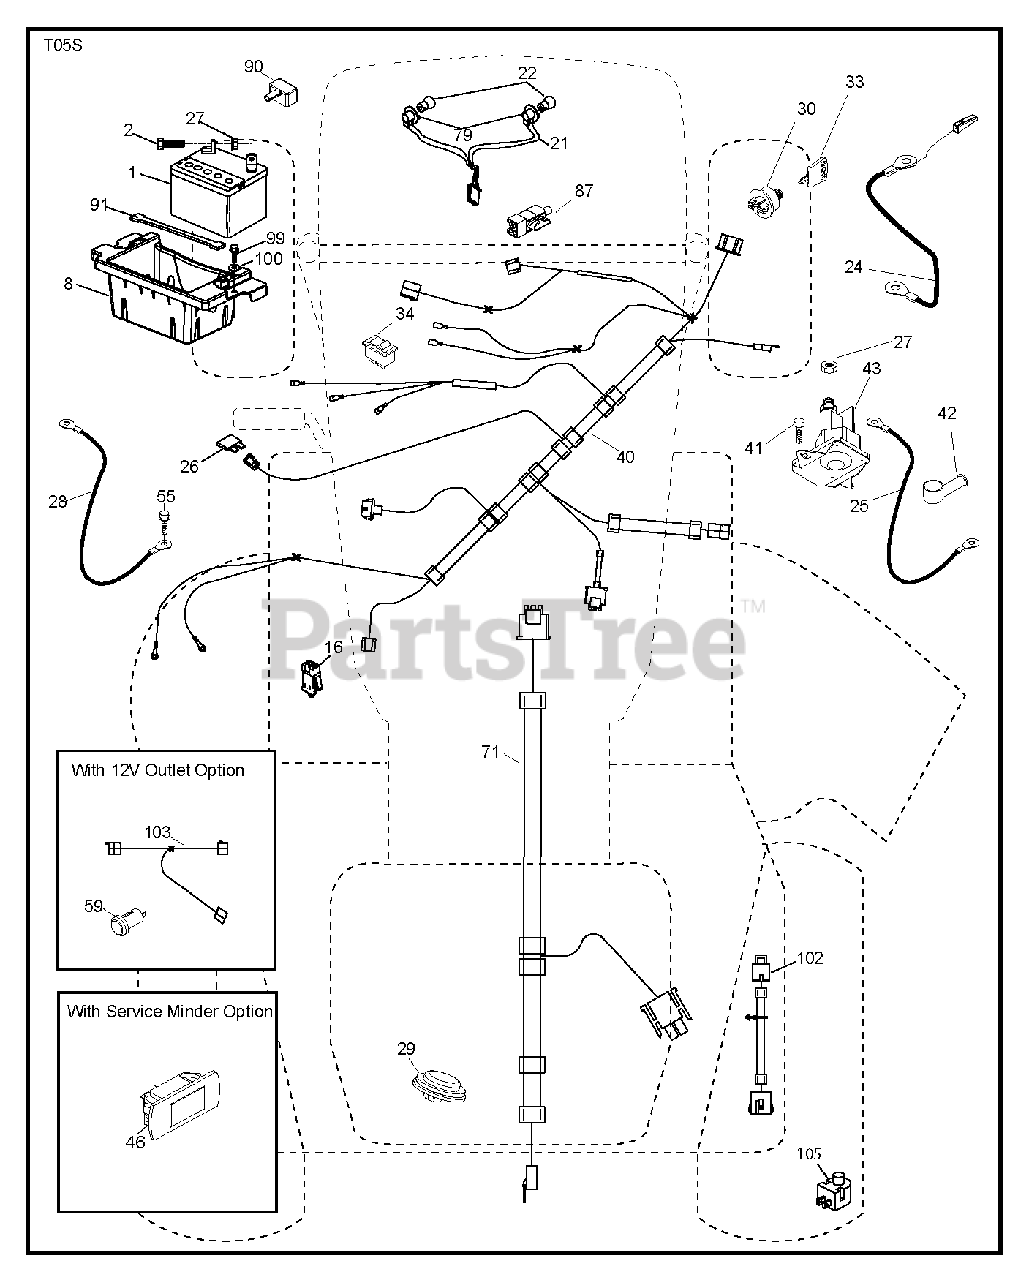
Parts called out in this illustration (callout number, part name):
1	REPL BY 532 12 38-99
2	BOLT.HEX.1/4.X.3/4.DICHROMATE
8	BOX.BATTERY.MOUNT.FRONT.LT
16	SWITCH INTERLOOK PUSH-IN
21	HARNESS ASSY LIGHT
22	LIGHTBULB
24	Battery Cable with Wire, Front 8 Ga 8
25	CABLE.STARTER.6GA.BL/RED.14.
26	FUSE 20AMP
27	NUT
28	Ground Cable, 21" Black 8 Ga 90T
29	SWITCH.SEAT.DELTA.OPC.
30	SWITCH.IGN.DELTA.W.LGH.ROS
33	KEY.CHAIN.BLISTER.PACK.GEN.INT
34	SWITCH LT
40	HARNESS IGN. DASH
41	SCREW
42	TERMINAL COVER
43	SOLENOID.W/BRASS.PLUNGER
46	GUAGE.SRVCMNDR.HRMTR.
55	SCREW 5/16"
71	HARNESS-CHASSIS SUB
79	BULB HOLDER ASM.
87	SWITCH.INTRLCK.CLUTCH.
90	COVER.TERMINAL.BATTERY
91	STRAP.BATTERY.MOUNT.FRONT
99	SCREW HEXWSHR 1/4-20X3/4
102	HARNESS.PIGTAIL.VARIATOR.SD
105	REVERSE SWITCH
